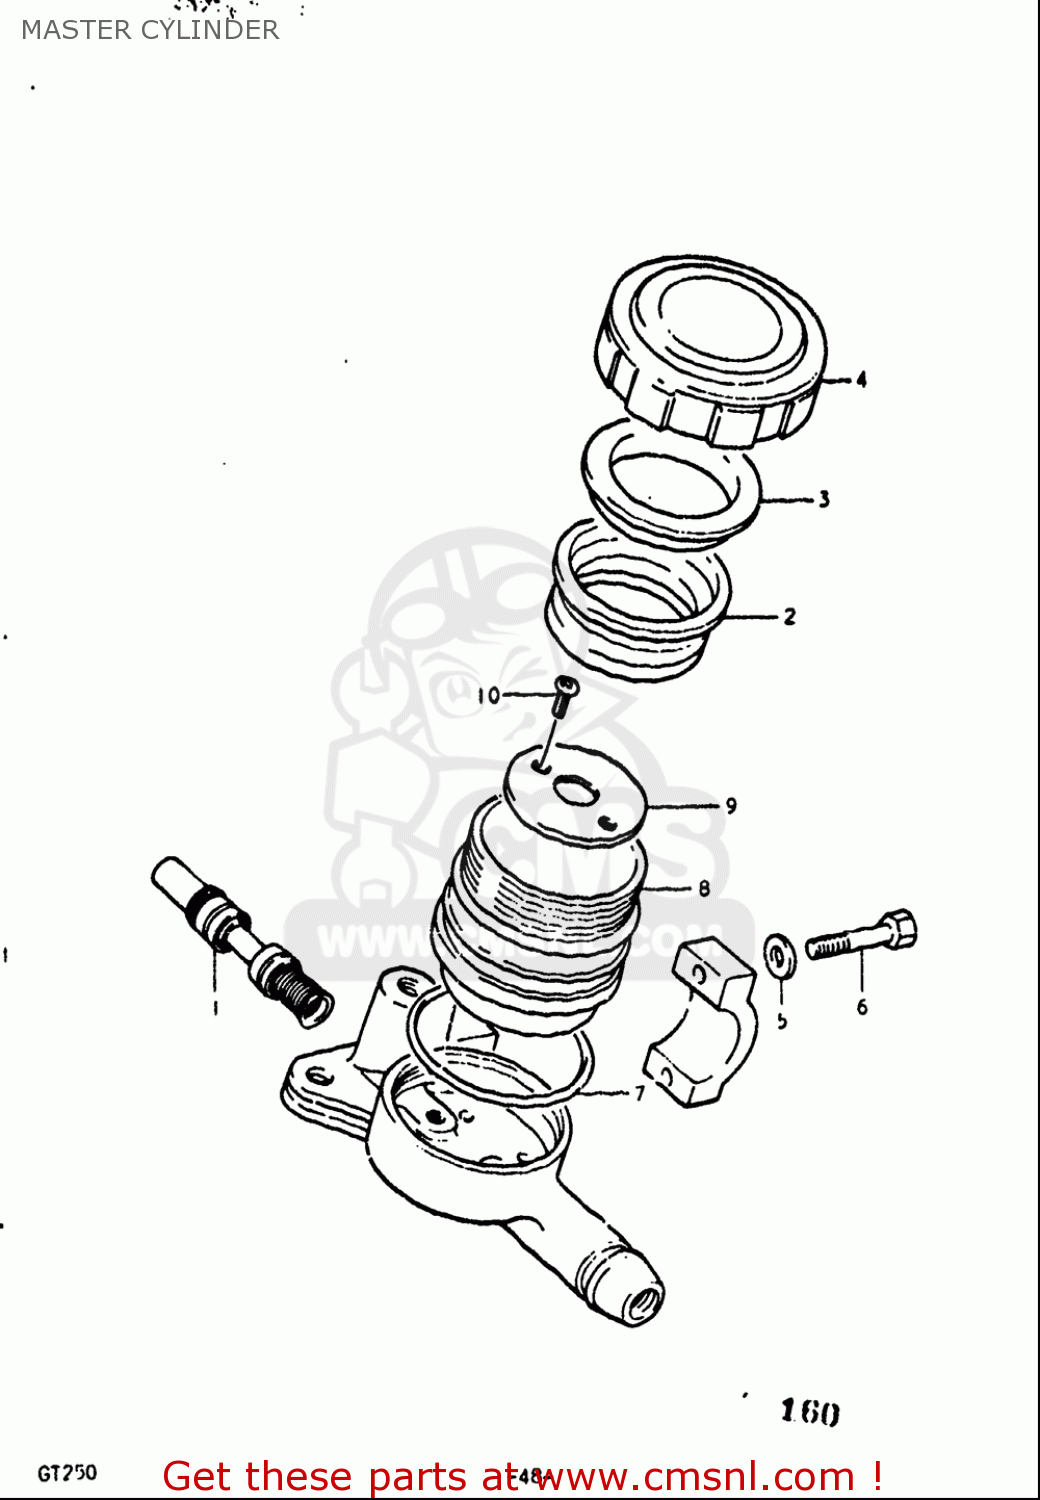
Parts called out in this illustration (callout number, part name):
1	PISTON & CUP SET
2	DIAPHRAGM
3	PLATE,DIAPHRAGM
4	CAP
5	WASHER
6	BOLT
7	O RING
8	RESERVOIR
10	SCREW
